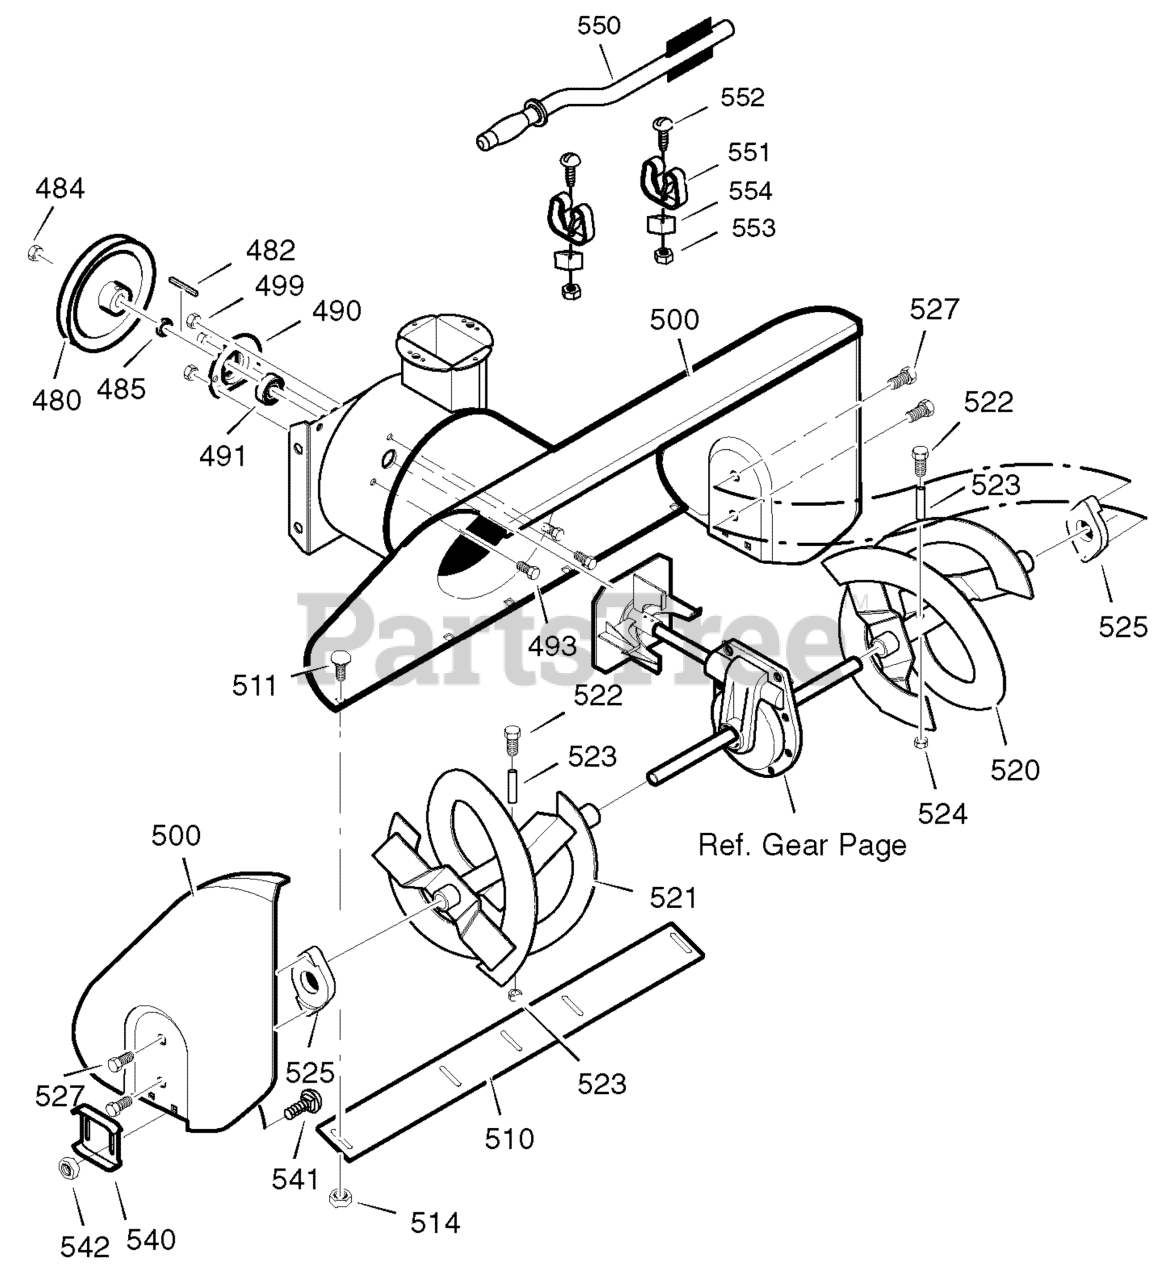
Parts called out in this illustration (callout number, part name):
480	PULLEY
482	KEY, SQUARE
484	NUT, 1/4-20
485	SPACER, FRICTION PULLEY
490	RETAINER, BALL BRNG
491	BEARING, BALL
493	BOLT, HEX - 0.31-18X0.50
499	NUT, 5/16-18 HEX
500	HOUSING, ASSY
510	BLADE, SCRAPER
511	BOLT, 1/4-20X.75
520	AUGER, ASSY, LH
521	AUGER, ASSY, RH
522	SCREW, 1/4-20X1.75
523	SPACER, SLEEVE
524	NUT, 1/4-20
525	BEARING,FLANGE
527	SCREW, 5/16-18 x 0.75
540	SKID, HEIGHT ADJUST
541	BOLT, 5/16-18 X .75
542	NUT, 5/16-18 REGHEX
550	BRUSH, CLEANOUT
551	CLIP, RETAINER
552	SCREW
554	BLOCK
